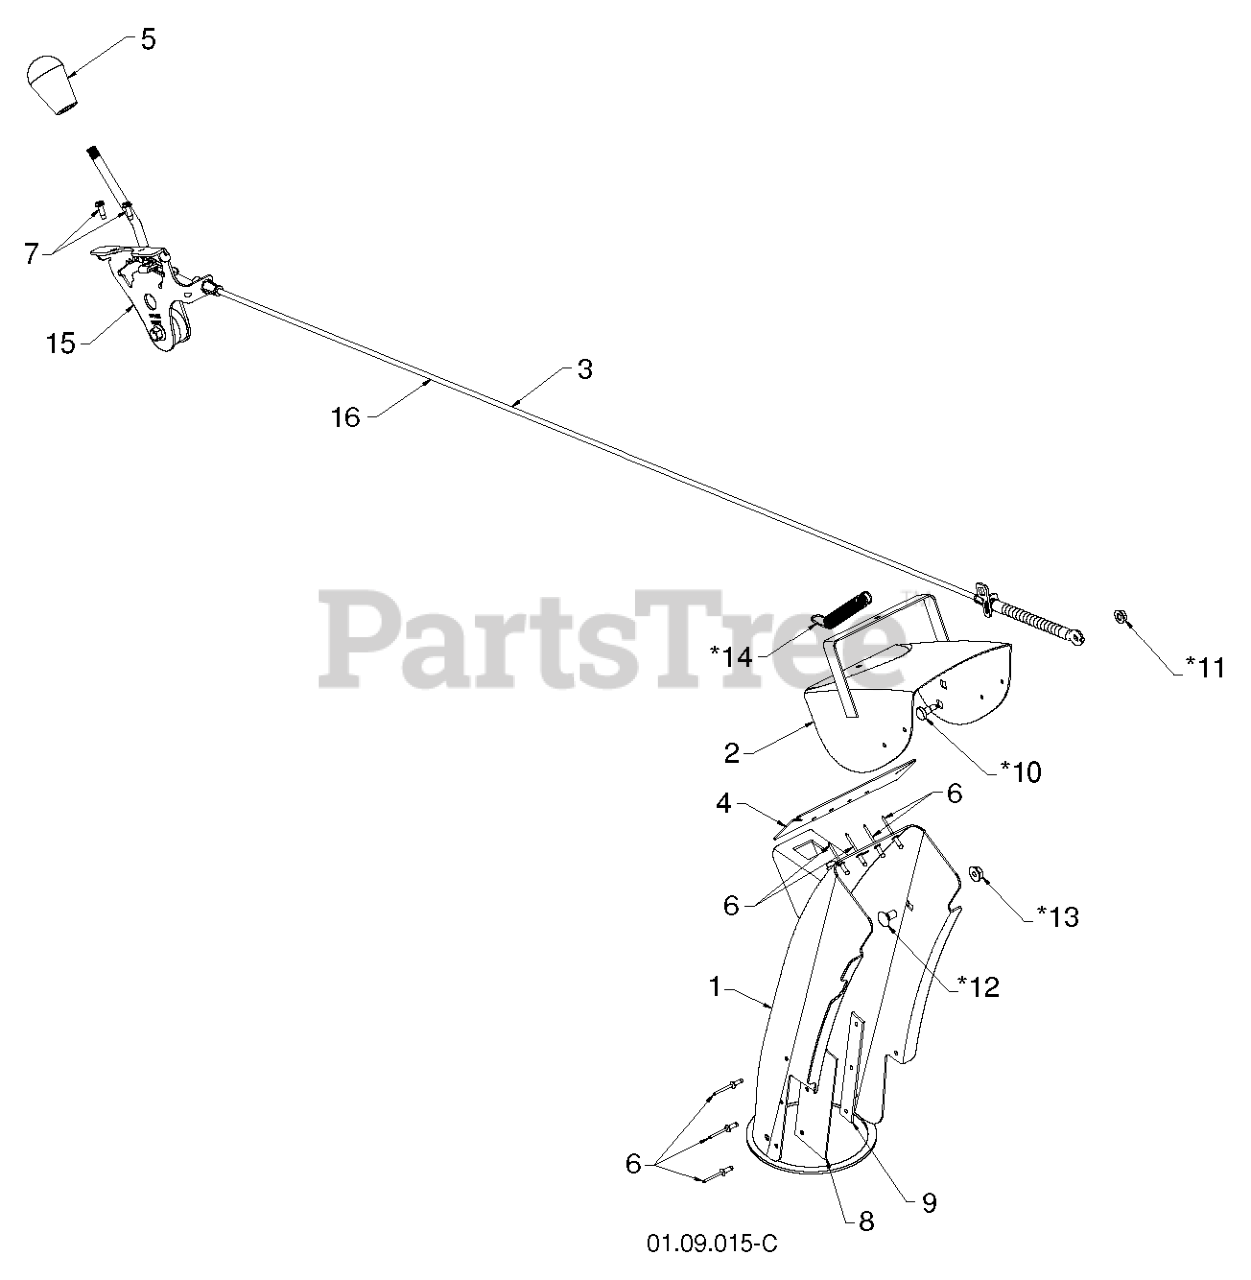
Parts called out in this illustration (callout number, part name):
1	CONTROL.DRIVE.S/SPEED.FWGD
6	SPRING RETAINER
7	BAIL.CONT.DR.S/S.ROUND.ORG
11	WHEEL.8X1.75.H3SPK.RAD3.GY.BU3
12	E-RING 7/16 RE
13	PINION.14.TEETH.FGD
14	COVER.DUST.WHEEL
15	PAWL, DRIVE
16	WASHER FLUT
17	BEARING
18	SELECTOR KNOB
27	SCREW, HEX HD TAPPING #10-24 1
28	COVER.DRIVE.TORUS.B&S.MOLDED
29	NUT.HEX.FLANGE.3/8-16.LO(3 2)
31	SCREW.PAN.HEAD.#10
33	BELT THERM .32
34	PANEL.TRIM.21.FWGD.ES
35	RP KIT, WHEEL ADJUSTER, LH
36	TRANSMISSION.22.FGD/W/PULLEY
37	BATTERY WITH AMP CONECTOR AGM
38	LOCKNUT.NYLOC.1/4-20
39	BOX.BATTERY.TRIM
40	SPRING.EXTENSION
41	KIT, WHEEL ADJUSTER, RH
42	SCREW.HWH.13-16X.50
44	SCREW.SHOULDER.HH.10X.281X.6
45	RP CHARGER.BATTERY
54	GBAG.83230247T.SIL.HUSQ.BLU
56	PANEL.ASM.TRIM/BATTERY.BOX
57	FRAME.GBAG.22.EZ.EMPTY.SC
